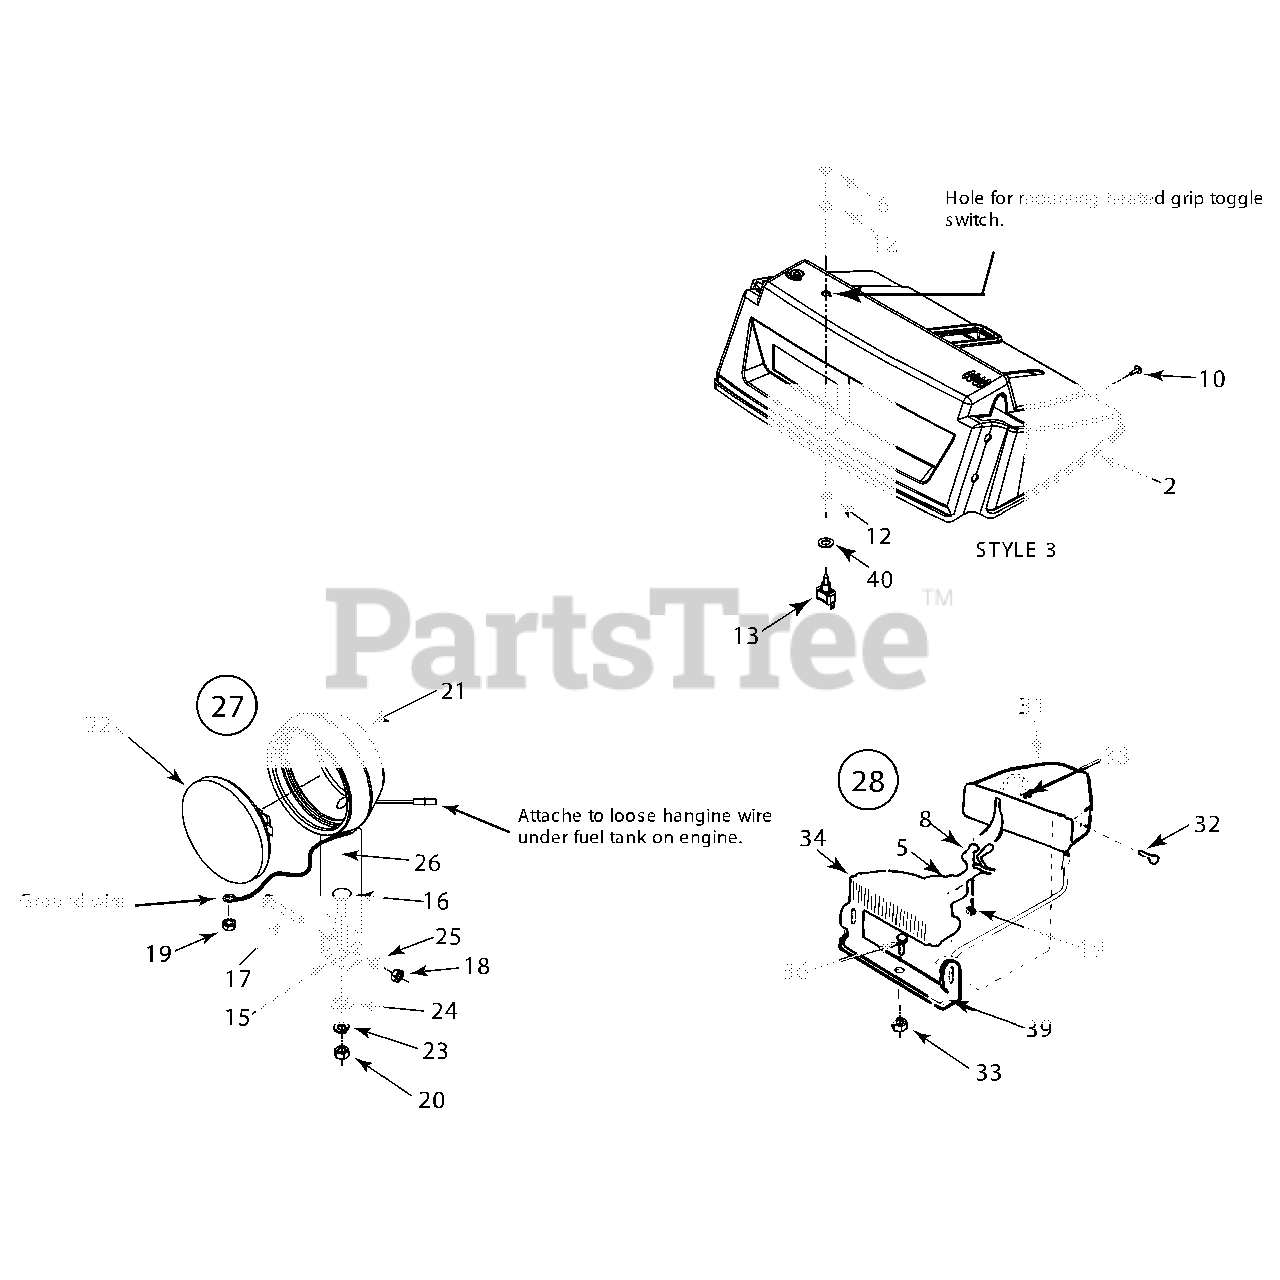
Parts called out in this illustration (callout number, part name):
2	Yellow Handle Panel (w/hole for top mounting light and chute tilt cut out) STYLE 3
2	Yellow Handle Panel (w/light cut and chute tilt cut out and heated grips) STYLE 3
4	Black Handle Panel (w/light cut and chute tilt cut out and heated grips)
5	Bulb #890, 12 V, 27 Watt
5	Bulb, #886, 12 V, 50 Watt (Style 3 w/heated grips)
6	Hex Nut
7	Headlight Housing
8	Wire Harness
9	Retainer
10	Hex Tapp Wash Hd. Scr. #10 x 5/8
12	Lock Ring - Toggle Switch
13	Toggle Switch,Single Throw (heated grips)
15	Mounting Lamp Bracket
16	Carriage Bolt 5/16-18 x 1.00" Lg
17	Hex Screw 1/4-28 x 1.75 Gr 5
18	Hex Nut 1/4-28 Gr 5
19	Sems Hex Nut 1/4-20
20	Hex Nut 5/16-18 hd. Gr. 5
21	Lamp Housing
22	Sealed Beam 18 Watt CGE #4414-1
23	L-Wash 5/16 ID
25	L-Wash 1/4 ID
26	Ground Wire (Purchase locally)
27	Top Mount 18 watt Lamp Ass’y (sealed beam)
28	Top Mounting Halogen Lamp Assembly
31	Halogen Lamp Housing
32	Phillips Pan Hd. Scr. M4 x 16mm
33	Hex Flange Locknut 5/16-18 Gr. F Nylon
34	Lamp/Lens Housing Ass’y
36	Carriage Bolt 5/16-18 x .75
38	Grommet .38 ID X .50 OD X .12
39	Lamp Mounting Brkt.
40	Flat Washer .474 ID x .879 OD x .064
